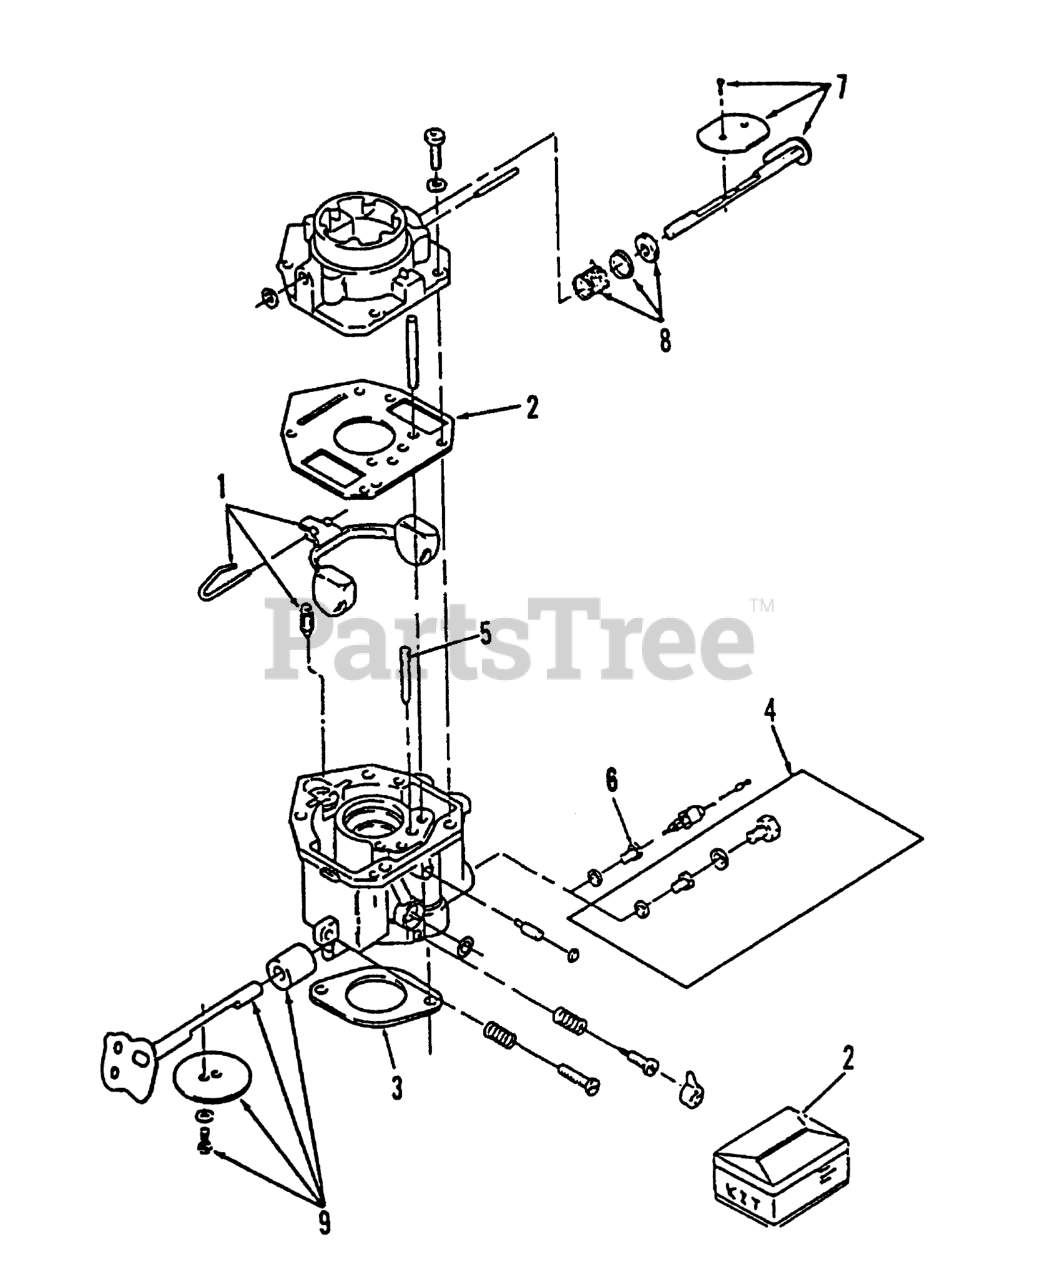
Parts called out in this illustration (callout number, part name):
1	Kit-Float (Includes Float, Pin, & Valve)
2	Kit-Repair (Includes Screw & Plug Package, Gasket Package, Float Valve, Idle Adjustment Needle & Spring, Mounting Gaskets, & Idle Limit Cap)
3	GASKET-CARBURETOR
4	FIXED-JET PKG
5	Idle Jet
6	POWER JET
7	Kit-Choke Shaft (Includes Choke Valve, Valve Screw-Set, & Air Filter)
8	Kit-Choke Lever (Include Choke Lever Ring, Choke Spring, & Choke Collar)
9	Kit-Throttle Shaft (Includes Valve Screw-Set, Air Filter, & Throttle Valve)
